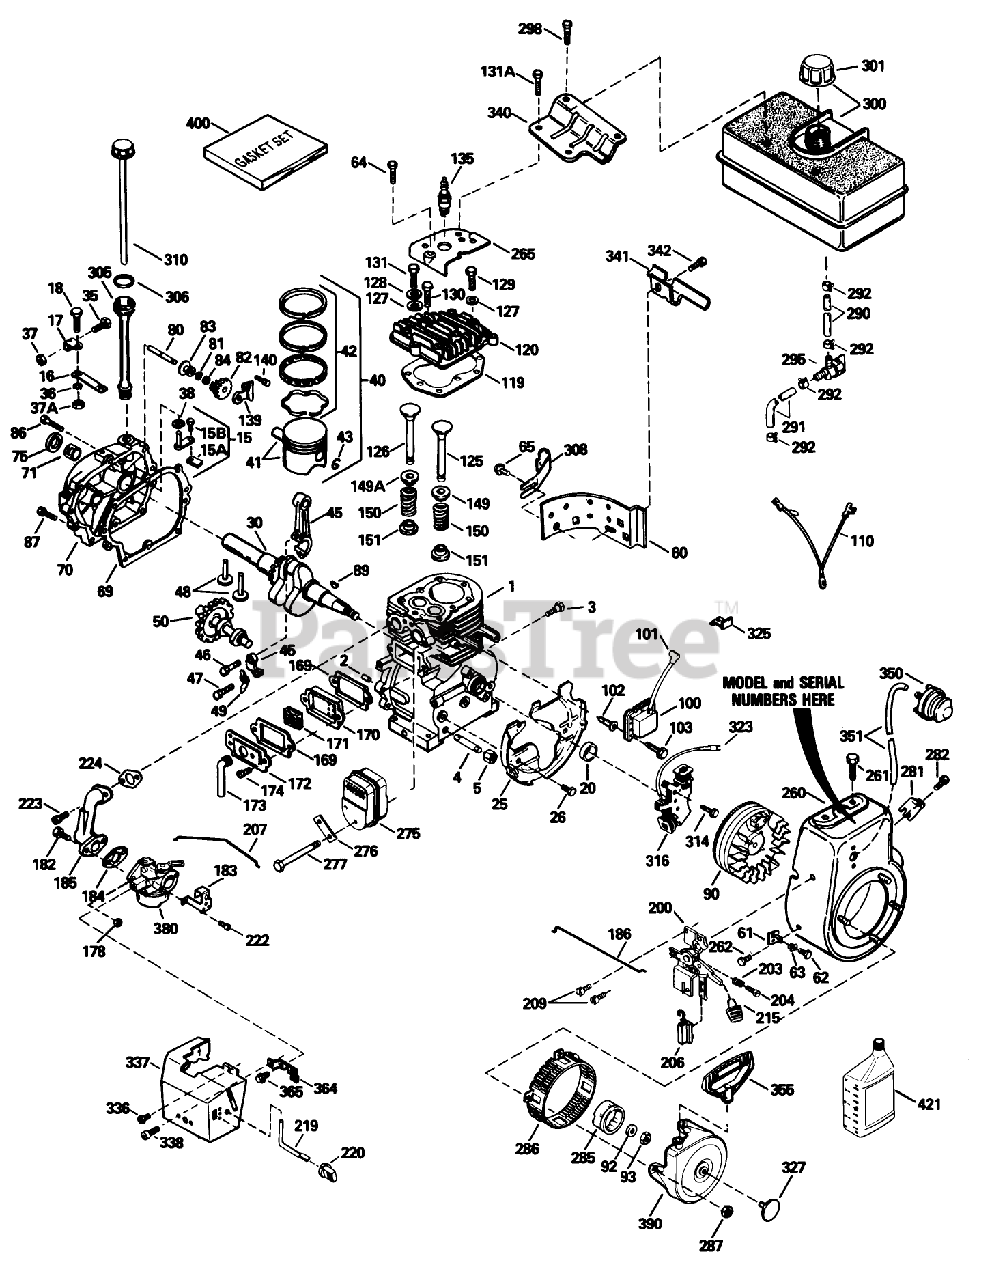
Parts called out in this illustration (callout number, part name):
1	Cylinder (Incl. ref. #2 20)
2	Pin-Dowel
3	Screw (1/4-20x1/2)
4	Nipple-Pipe
5	Cap-Pipe
15	Rod, Governor (Incl. Nos.62 63)
15A	Yoke-Governor
15B	Screw (6-40x5/16)
16	Lever-Governor
17	Clamp-Lever, Governor
18	Screw
20	Seal-Oil
25	Baffle-Blower Housing
26	Screw (1/4-20x19/32)
30	Crankshaft
35	Screw
36	Washer-Lock
37	Nut-Lock
37A	Nut-Lock
38	Ring-Retaining
40	Piston, Pin Ring Assy. Std.(Includes ref. #41, 42 43)
41	Piston Pin Assembly Standard (Includes ref. #43)
42	Ring Set (STD)
43	Retaining Ring-Piston Pin
45	Rod Assembly-Connecting (Incl. ref. #46, 47 49)
46	Bolt-Rod
47	Bolt-Rod
48	Lifter-Valve
49	Dipper-Oil
50	Camshaft (MCR)
60	Extension-Housing, Blower
61	Bracket
62	Screw (8-32 x 3/8)
63	Grommet
64	Screw (1/2-20x5/8)
65	Screw
69	Cylinder Cover Gasket
70	Cover-Cylinder (Includes 71, 75, 80)
71	2025A77 WIZARD ROTA
75	Seal-Oil
80	Shaft-Governor
81	Washer-Flat
82	Gear Assy., Governor (Incl. Ref. #45)
83	Spool-Governor
84	Ring-Retaining
86	Screw (1/4-20x1-3/16)
87	Screw (1/4-20x1-11/16)
89	Key-Flywheel
90	Flywheel ASM
92	Washer-Belleville
93	Nut-Flywheel
100	Solid State ASM
101	Cover-Spark Plug
103	Screw
110	Ground Wire
119	Gasket-Cylinder Head
120	Head-Cylinder
125	Valve, Exhaust (Standard)(Incl. No. 9)
126	Valve, Intake (Std.) (Incl. Ref. #58)
127	Washer-Flat
128	Washer-Belleville
129	Screw (5/16-18x1-25/32)
130	Screw
131	Screw (5/16-18 X 2)
131A	Screw
135	Spark Plug-Resistor (R J19 L M)
139	Bracket-Gear, Governor
140	Screw (10-24x1/2)
149	Cap-Spring, Valve
149A	51106 GILSON ROTARY
150	Spring-Valve
151	Keeper-Spring, Valve
169	Gasket-Cover, Valve
170	Body-Breather
171	Element-Breather
172	Cover-Valve
173	Tube-Breather
174	Screw
178	Nut and Lock Washer (1/4-28)
182	Screw (1/4-28x1)
183	Bracket-Choke
184	Gasket-Pipe, Intake
185	Pipe-Intake
186	Link-Governor
200	Bracket-Control (Includes 19, 203, 204, 206)
203	Spring-Compression
204	Screw
206	Terminal
207	Link-Throttle
209	Screw (10-32 x 1/2)
215	Knob-Control
219	Rod-Choke
220	Knob-Control
222	Screw (10-32 x 1/2)
223	Screw (T-30, 5/16-18x1-3/32)
224	Gasket-Carburetor To Intake Pipe
260	Housing-Blower
261	Screw (5/16-18x3/4)
262	Screw
265	Cover-Cylinder Head
275	Muffler
276	62513 SNWTHWR W/284
277	Screw
281	Screw
282	Screw (8-32 x 3/8)
285	Hub-Starter
286	Screen-Starter
287	Nut and Lock Washer (1/4-28)
290	Line-Fuel (8.62)
291	Line-Fuel
292	Clamp-Line, Fuel
295	Valve-Shut Off, Fuel
298	Screw (1/4-15x7/8)
300	Tank-Fuel (Includes 292, 301)
301	Cap-Fuel
305	Tube-Fill, Oil
306	O-Ring
308	Clip-Tube, Fill
310	Gauge Oil ASM
314	Screw (1/4-20 x 3/4)
316	Coil-Alternator, 18 Watt (Includes 323)
323	Terminal
325	Clip-Wire
327	Plug Starter
336	Screw (10-32x1/2)
337	Cover-Carburetor
338	Screw (10-32 x 3/8)
340	Bracket-Tank, Fuel
341	Bracket-Tank, Fuel (Black)
342	Screw (1/4-20x19/32)
350	Primer-Asm
351	Line-Primer
355	Handle-Starter, Mitten Grip
364	Bracket-Carburetor
365	Screw (8-32x27/64)
380	Screw-Hex Washer Hd.
390	Rewind Starter
400	Gasket Set (Incl. items marked *)
421	Oil-Engine (SAE 5W30)
